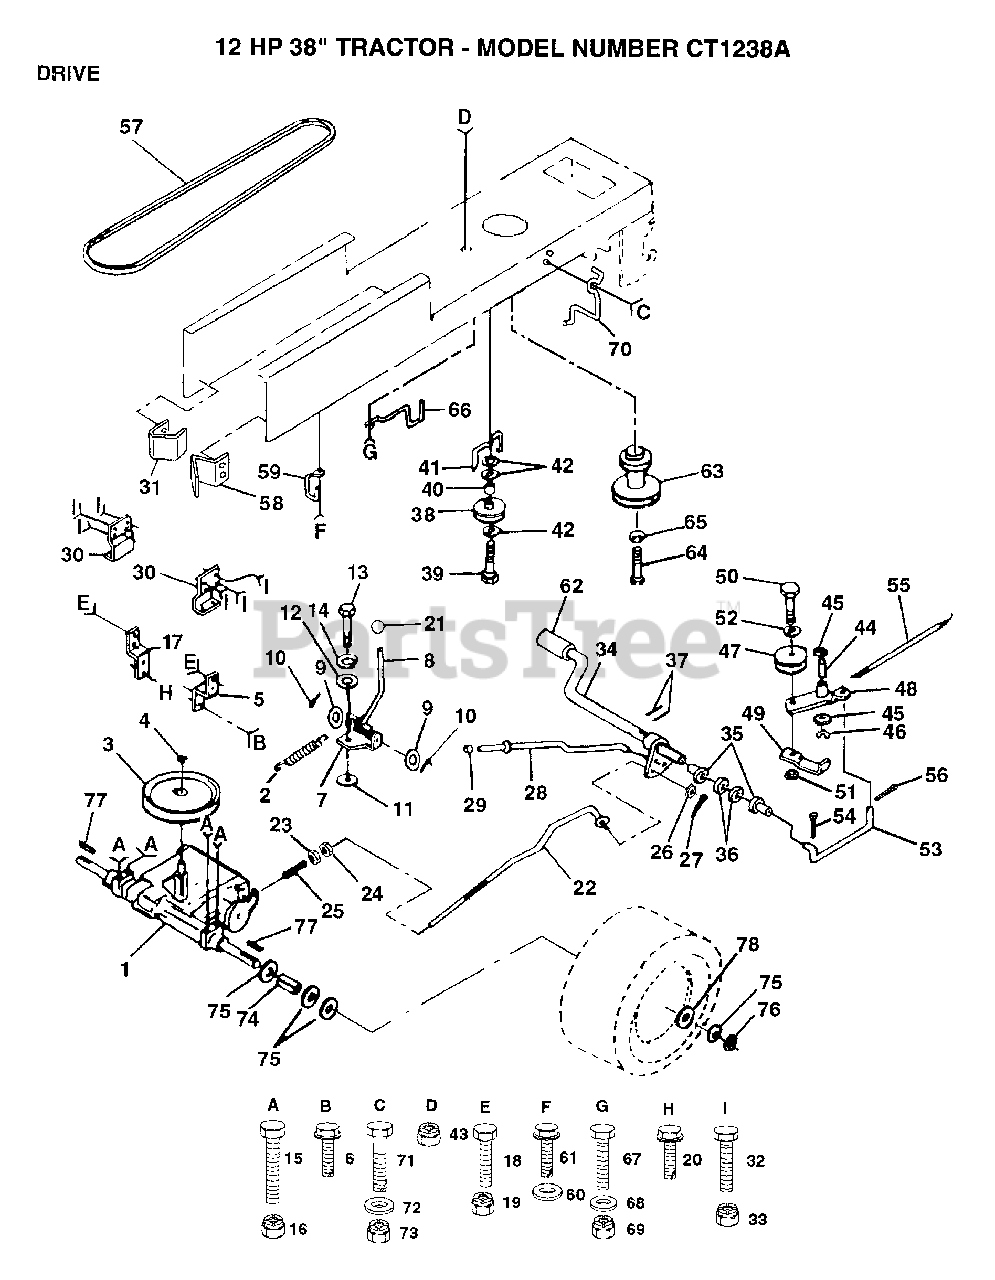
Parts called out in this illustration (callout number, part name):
1	TRANSAXLE 5SP
3	PULLEY TRANS
5	STRAP TORQUE
6	SCREW
7	PLATE SHIFT LT
8	ROD SHIFTER
9	WASHER
10	PIN COTTER 1/8
11	WASH-SHFT PLT LT
12	WASHER LT
14	LOCKWASHER
15	BOLT
17	STRAP TORQUE
20	SCREW
21	KNOB T (1/2-HOLE)
23	NUT
24	NUT
25	SPRING ROD LT
26	WASHER
27	COTTER PIN
28	PARKING BRAKE ROD
29	PLUNGER CAP T
30	BRACKET LT
31	"KEEPER,BELT LH T"
32	BOLT
35	NYLON BEARING
36	WASHER LT
38	PULLEY.IDLER.FLAT
39	BOLT
40	SPACER T
41	BELT KEEPER LT
42	WASHER
44	"LY, BEARING"
45	WASHER LT
46	KLIP RING
48	ARM IDLER
49	RETAIN BELT
52	WASHER
53	"LINK, CLUTCH T"
54	COTTER PIN
55	"SPRING, RETURN LT"
56	COTTER PIN
57	BELT-V.90.0.GD.DR
58	"KEEPER,BELT RH T"
60	WASHER
61	SCREW
62	PEDAL COVER T
64	BOLT
65	LOCKWASHER
66	KEEPER.BELT.ENG.L
67	BOLT
68	WASHER
70	KEEPER BELT ENG
71	BOLT
72	WASHER
74	SPACER LT
75	WASHER
76	E-RING LT
77	SQUARE KEY
78	WASHER
